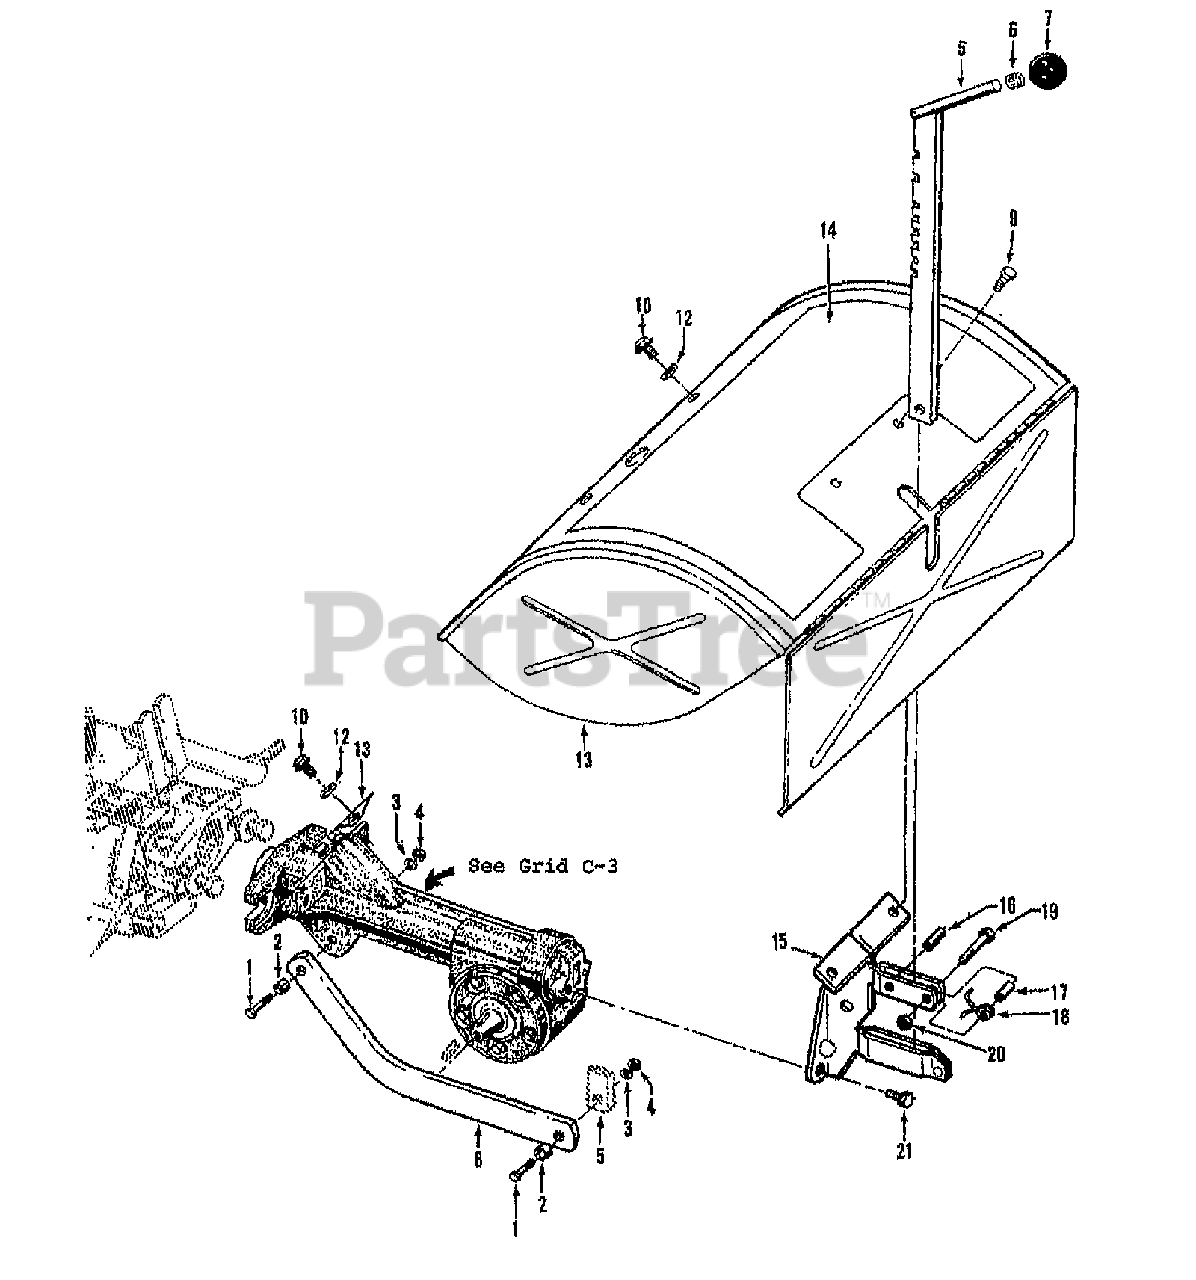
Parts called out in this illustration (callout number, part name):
1	SCR-HH 3/8-16X1.25
2	BUSHING-.5X.375X.3
3	WASHER-LK .375 @ DEPL
4	NUT-HEX 3/8-16 ZP
5	DEPTH REGULATOR W/KNOB
6	RING-TOLERANCE .5325 ID
7	KNOB-CONTROL
8	BAR-DRAG RED
9	SCR-HWH 1/4-20 X .5 STH
10	SCR-HFLK 5/16-18X.75 ZP
11	THIS REF. NO. NOT USED
12	WASHER-#1.125X.344 ZP
13	HOOD W/DECALS OPC SERVICE
14	DECAL-HOOD INST
15	BRKT W/ROLL PIN (9308)
16	PIN-ROLL .25 X 1
17	SPACER-.250X.343X.375
18	SPRING-TORSION
19	SCR-HH 1/4-20X1.0
20	NUT-LK 1/4-20
21	SCR-HFLK 5/16-18X.62 G5ZP
